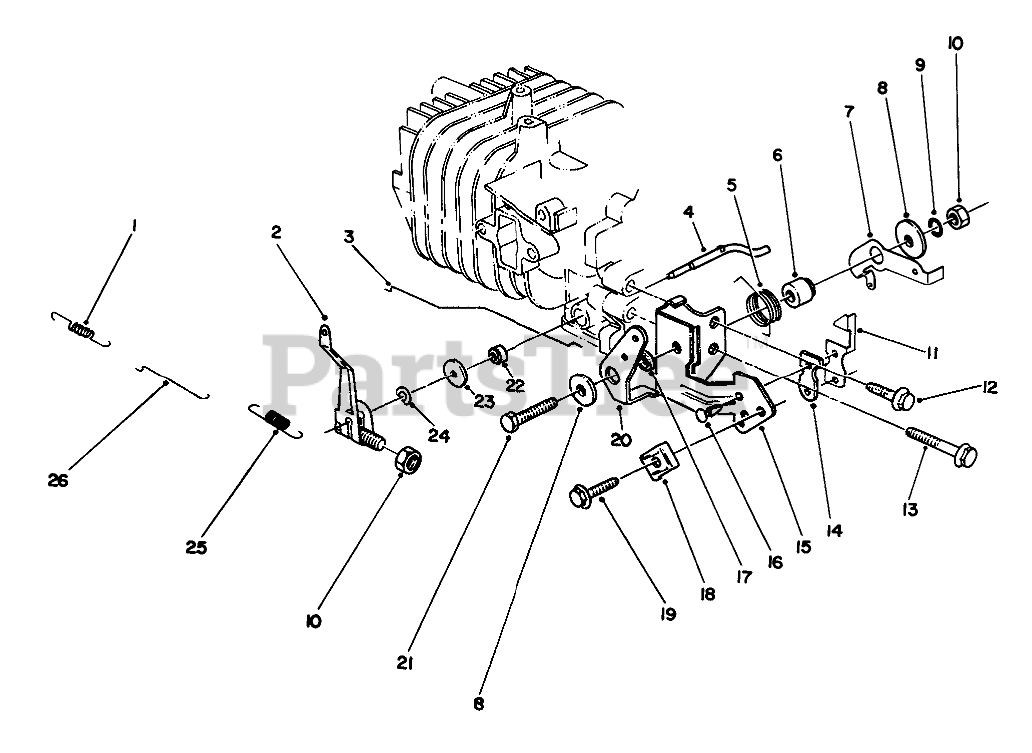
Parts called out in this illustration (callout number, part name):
1	SPRING
2	ARM-GOVERNOR
3	ROD-CHOKE
4	SHAFT
5	SPRING-CHOKE LEVER
6	Gov Lever Spacer
7	LEVER-SPRING, GOVERNOR
8	WASHER
9	LOCKWASHER
11	TERMINAL-KILL SWITCH
14	INSULATOR-KILL SWITCH
15	BRACKET-THROTTLE, CONTROL
16	RIVET
17	SPACER-CHOKE LEVER
18	CLAMP
20	LEVER-CONTROL, CHOKE
22	SEAL-OIL
23	WASHER
24	E-RING
25	SPRING-GOVERNOR
26	ROD-CARBURETOR
